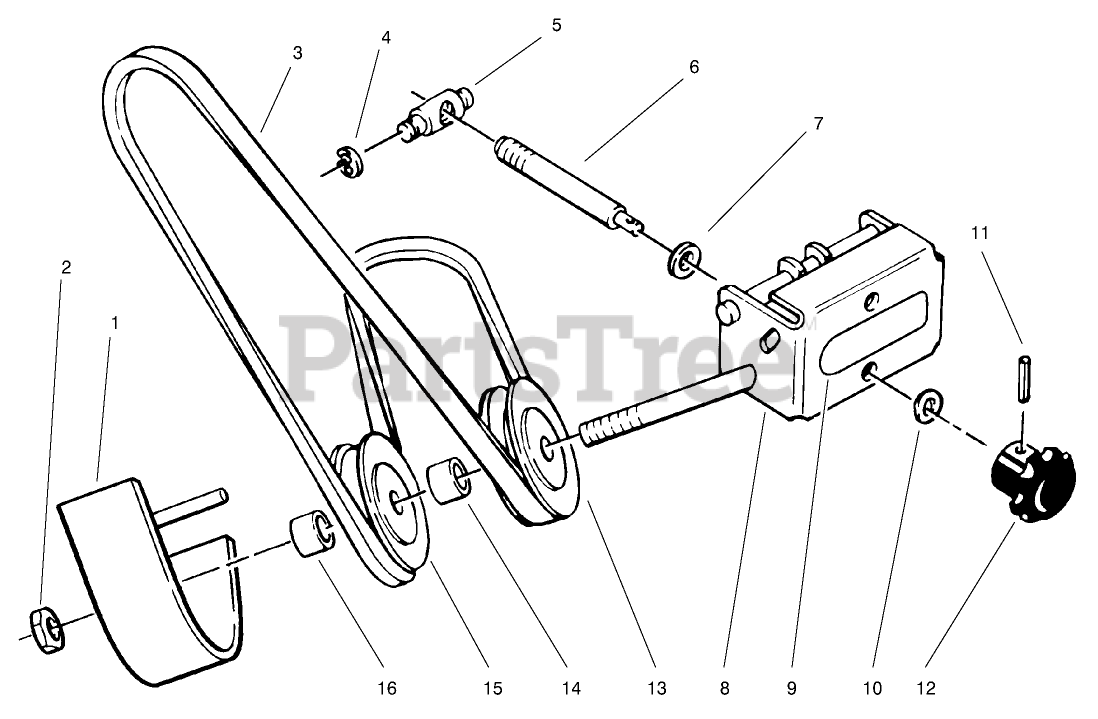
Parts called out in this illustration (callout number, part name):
1	COVER WA - BELT
2	NUT
3	V-BELT
4	RING-RETAINING
5	TRUNNION-DOUBLE
6	ROD ADJ
7	WASHER-FLAT
8	WA FRONT SUPPORT
9	DECAL-ATTACH A-MATIC
10	WASHER-SPRING
11	PIN-ROLL
12	KNOB-ADJUSTMENT
13	PULLEY-IDLER
14	SPACER
15	PULLEY-FLAT IDLER
16	SPACER-OUTER
